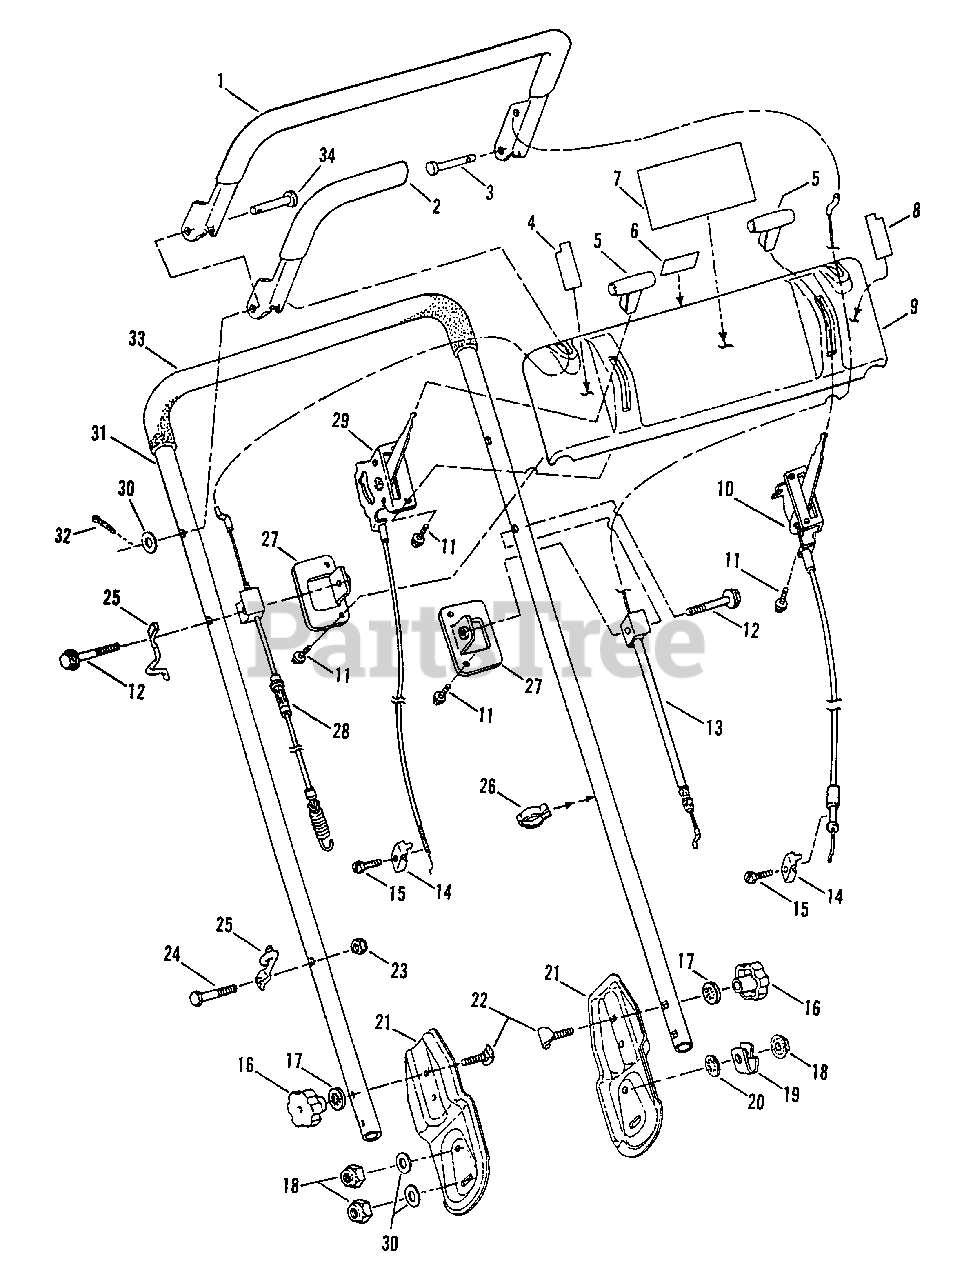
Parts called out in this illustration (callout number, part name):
1	CONTROL, Blade
2	CONTROL, Traction
3	PIN, 5/16 x 1-7/16" Clevis
4	DECAL, Engine Speed
5	KNOB, Throttle Control & 3-Speed Control
6	DECAL, OPC/SP Instruction
7	DECAL, Console
8	DECAL, 3-Speed Control
9	CONSOLE, Control
10	CONTROL ASSEMBLY, 3-Speed
11	SCREW, #10-16 x 1/2" Hex Washer Head, Self-Tapping
12	SCREW, 1/4-20 x 2 Hex Washer Head, Self-Tapping
13	CABLE ASSEMBLY, Blade Control
14	CLAMP, Throttle
15	SCREW, #10-32 x 5/8" Slotted Hex Head, Self-Tapping
16	KNOB, 5/16-18 Thread
17	WASHER, 5/16 Internal Tooth Lock
18	NUT, 5/16-18 Hex Nyloc
19	CLAMP, Double Tube
20	RETAINER, 5/16 Bolt
21	BRACKET, Handle
22	SCREW, 5/16-18 x 2 Curved Head
23	NUT, 1/4-20 Hex Nyloc
24	SCREW, 1/4-20 x 1 1/2 Hex Head Cap, Grade 5
25	GUIDE, Rope
26	CLAMP, Cable
27	BRACKET, Console
28	CABLE, Traction
29	CONTROL, Throttle
30	WASHER, Flat, .343 I.D. x.688 O.D.
31	HANDLE, Upper
32	COTTER-PIN, 3/32" x 1/2"
33	GRIP, Foam
34	PIN, 5/16 x 1.71" Clevis
